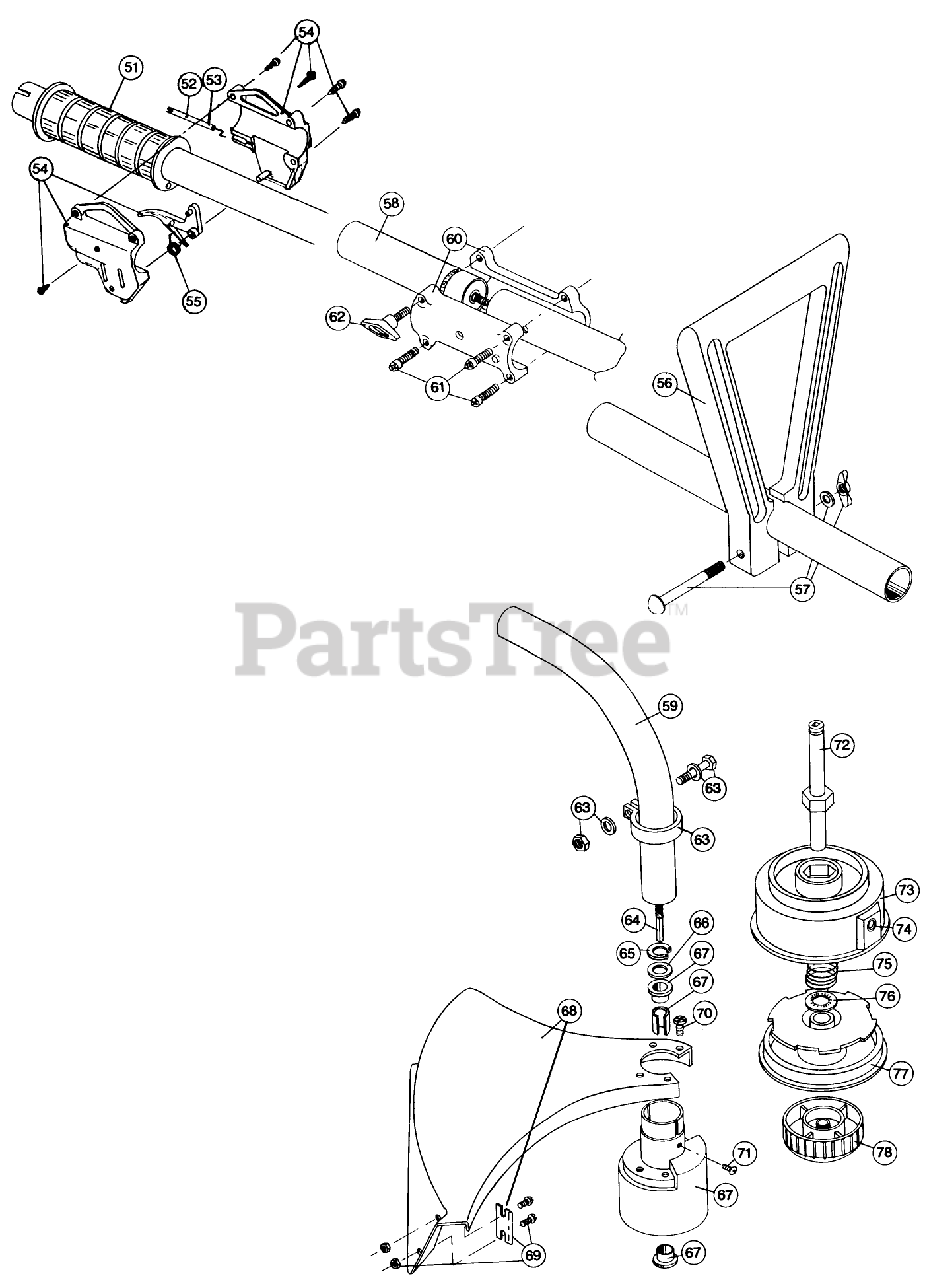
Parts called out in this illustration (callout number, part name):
52	THROTTLE CABLE HSG
53	THROTTLE CABLE WIRE
54	THROTTLE TRIGGER ASM
55	THROTTLE TRIGGER SPRING
65	RETAINING RING
67	BUSHING HSG ASM
69	BLADE ASM
70	GUARD MOUNTING SCREW
71	ANTI-ROTATION SCREW
76	RETAINER WASHER
77	REEL - INNER
